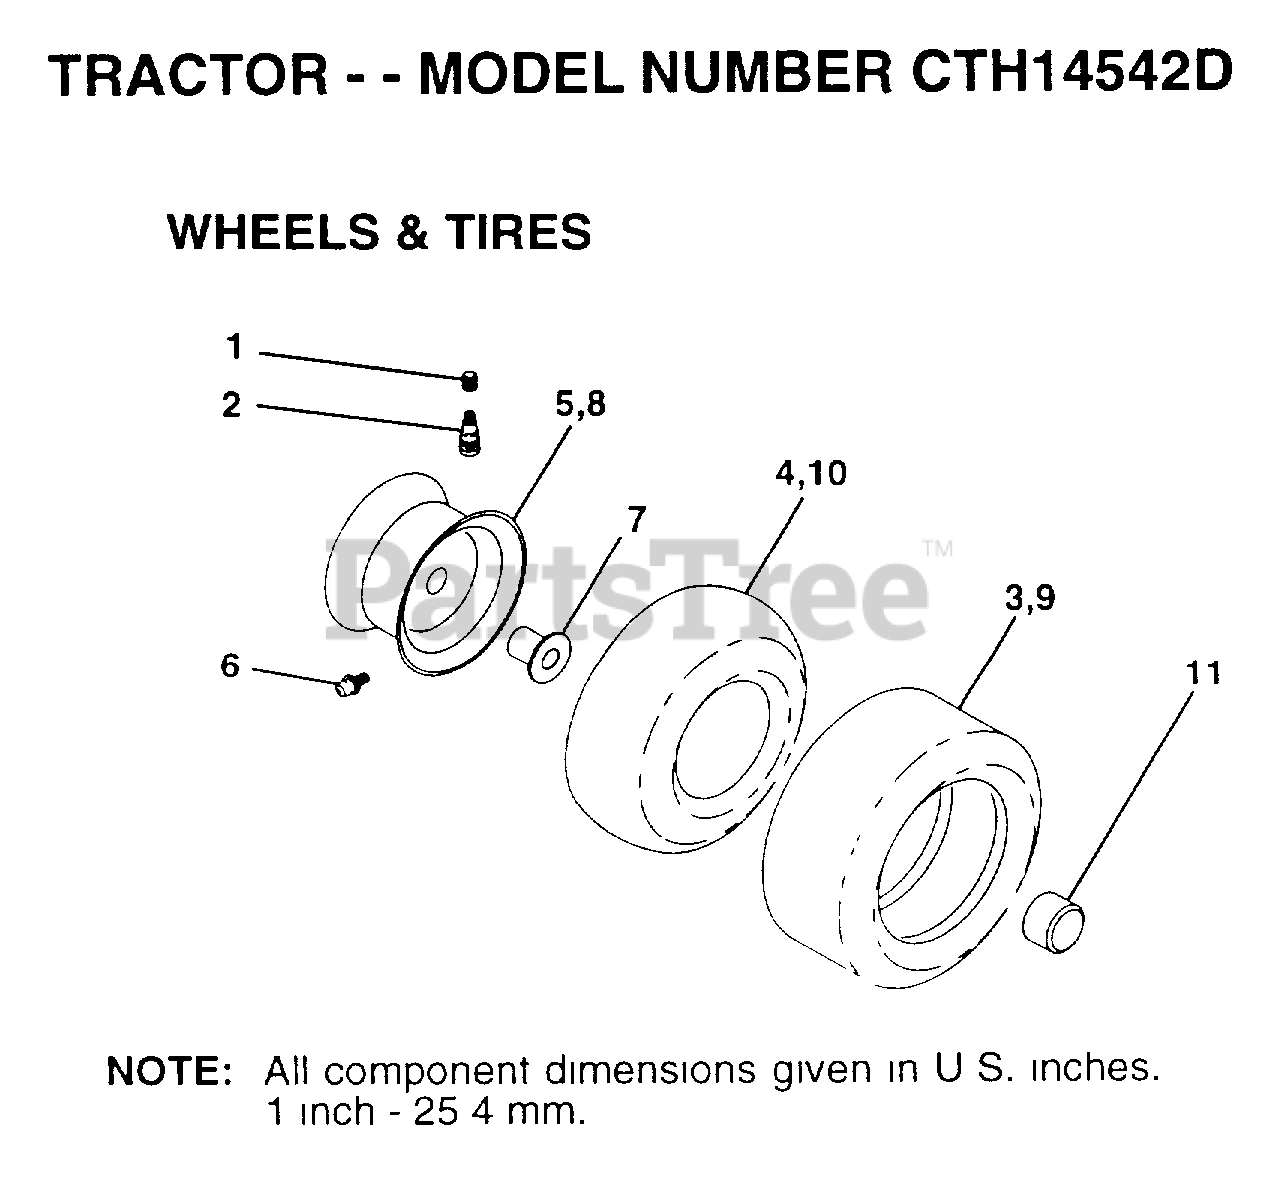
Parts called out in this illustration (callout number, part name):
1	VALVE CAP
2	VALVE STEM LT
4	TUBE.5.3/4.5/6
5	RIM.FRONT.6.YELLO
6	FITTING LT
7	"FLANGE, BEARING"
10	TUBE.18X9.5-8
11	HUB CAP
